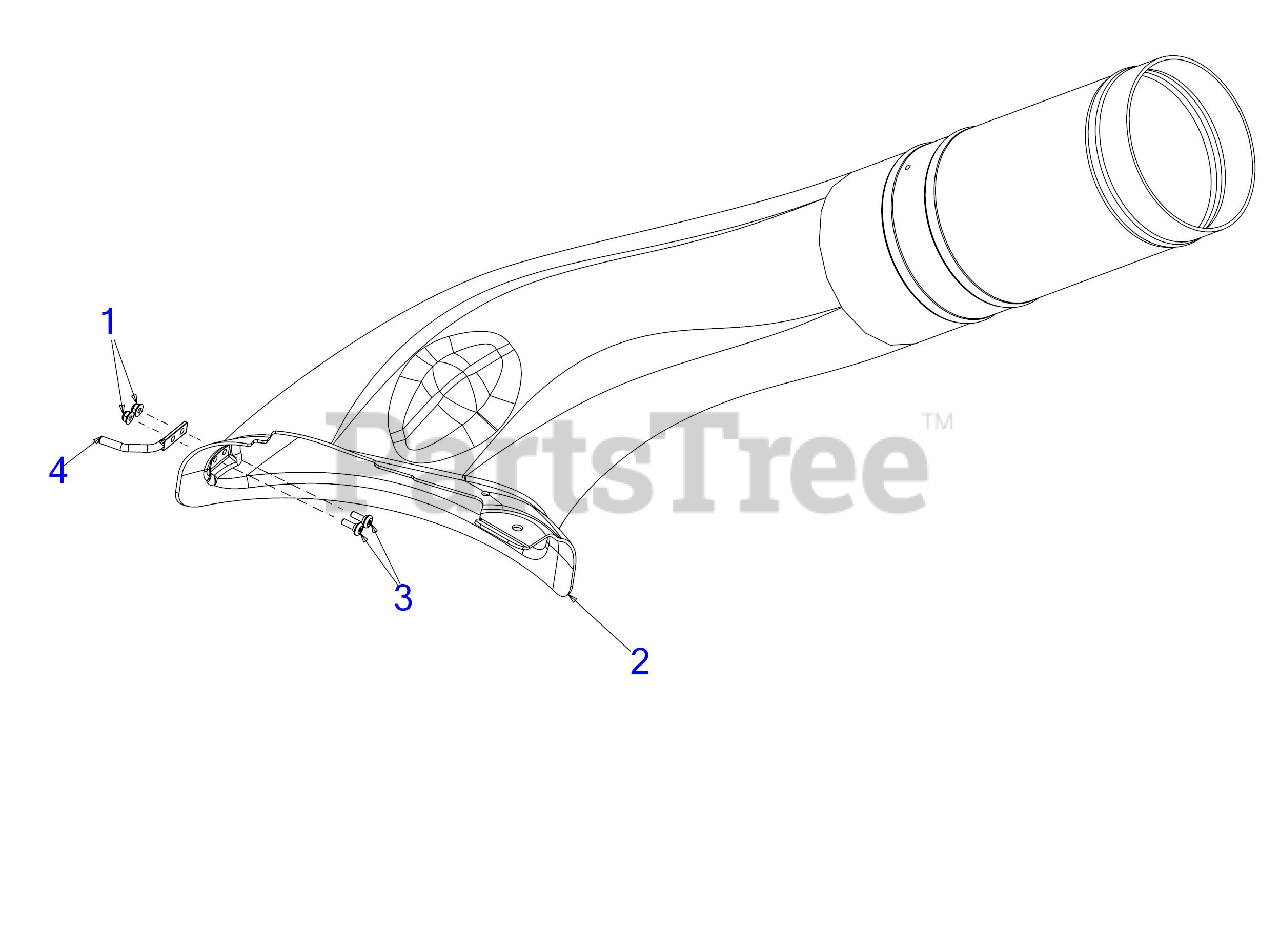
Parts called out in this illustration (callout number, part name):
1	FLANGE LOCK NUT
2	LOWER BAGGER CHUTE
3	SCR-SHLDR 1/4-20 x .75 TORX
4	LOWER CHUTE MOUNTING ROD
